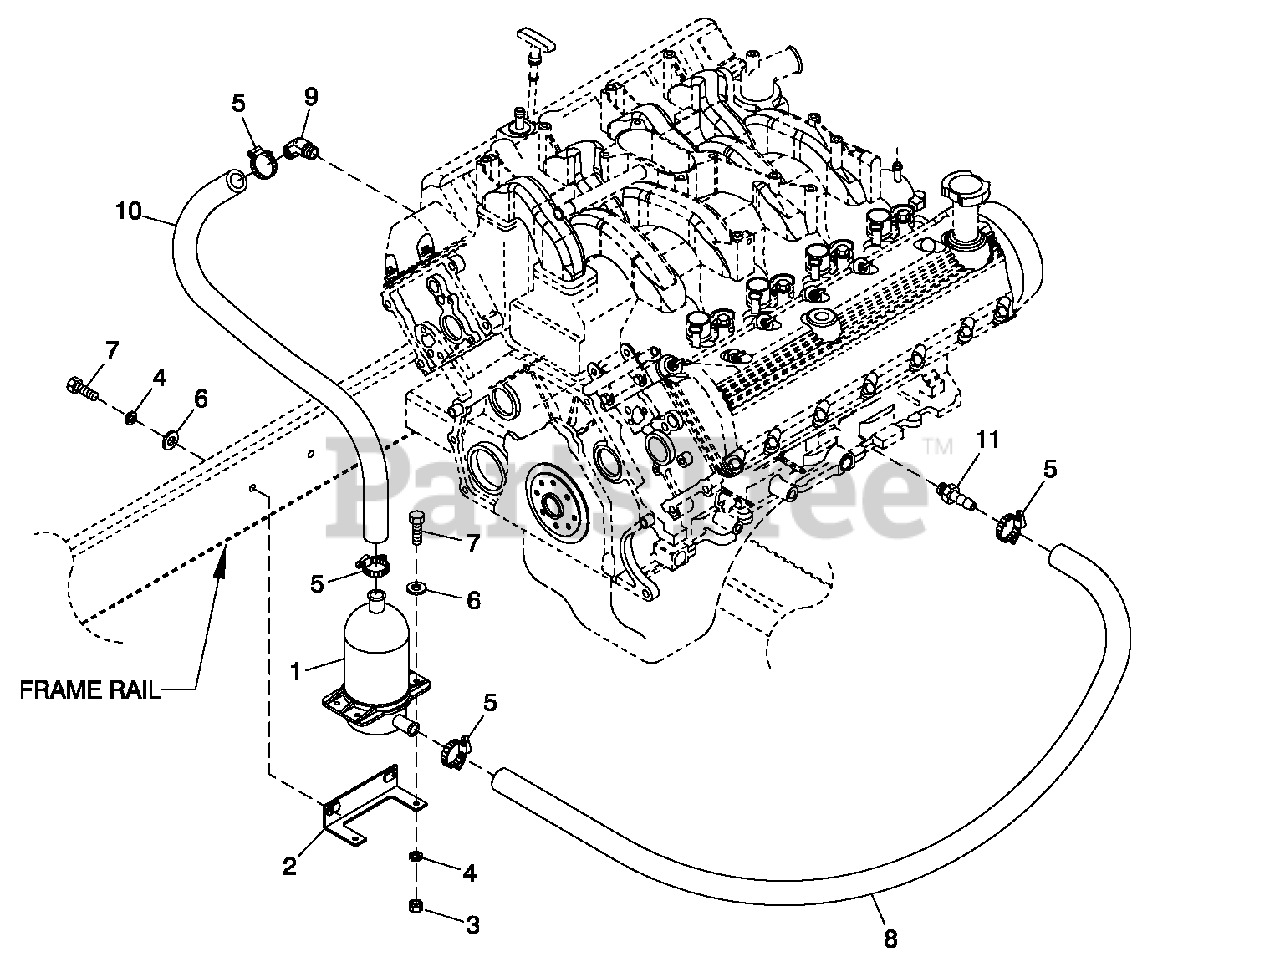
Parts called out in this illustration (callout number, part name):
1	HEATER BLOCK 2000W 240V
2	BRACKET HEATER W/WELDNUTS
3	NUT HEX M6 X 1.0 G8 YEL CHR
4	WASHER LOCK M6-1/4
5	CLAMP HOSE #8 .53-1.00
6	WASHER FLAT 1/4-M6 ZINC
7	SCREW HHC M6-1.0 X 20 G8.8
8	HOSE COOL 5/8 ID 20R3 (24" LG)
9	BARBED EL 45 3/8 NPT X 5/8 OD
10	HOSE PREFORMED BLOCK HEATER
11	BARBED STR 3/8 NPT X 5/8
